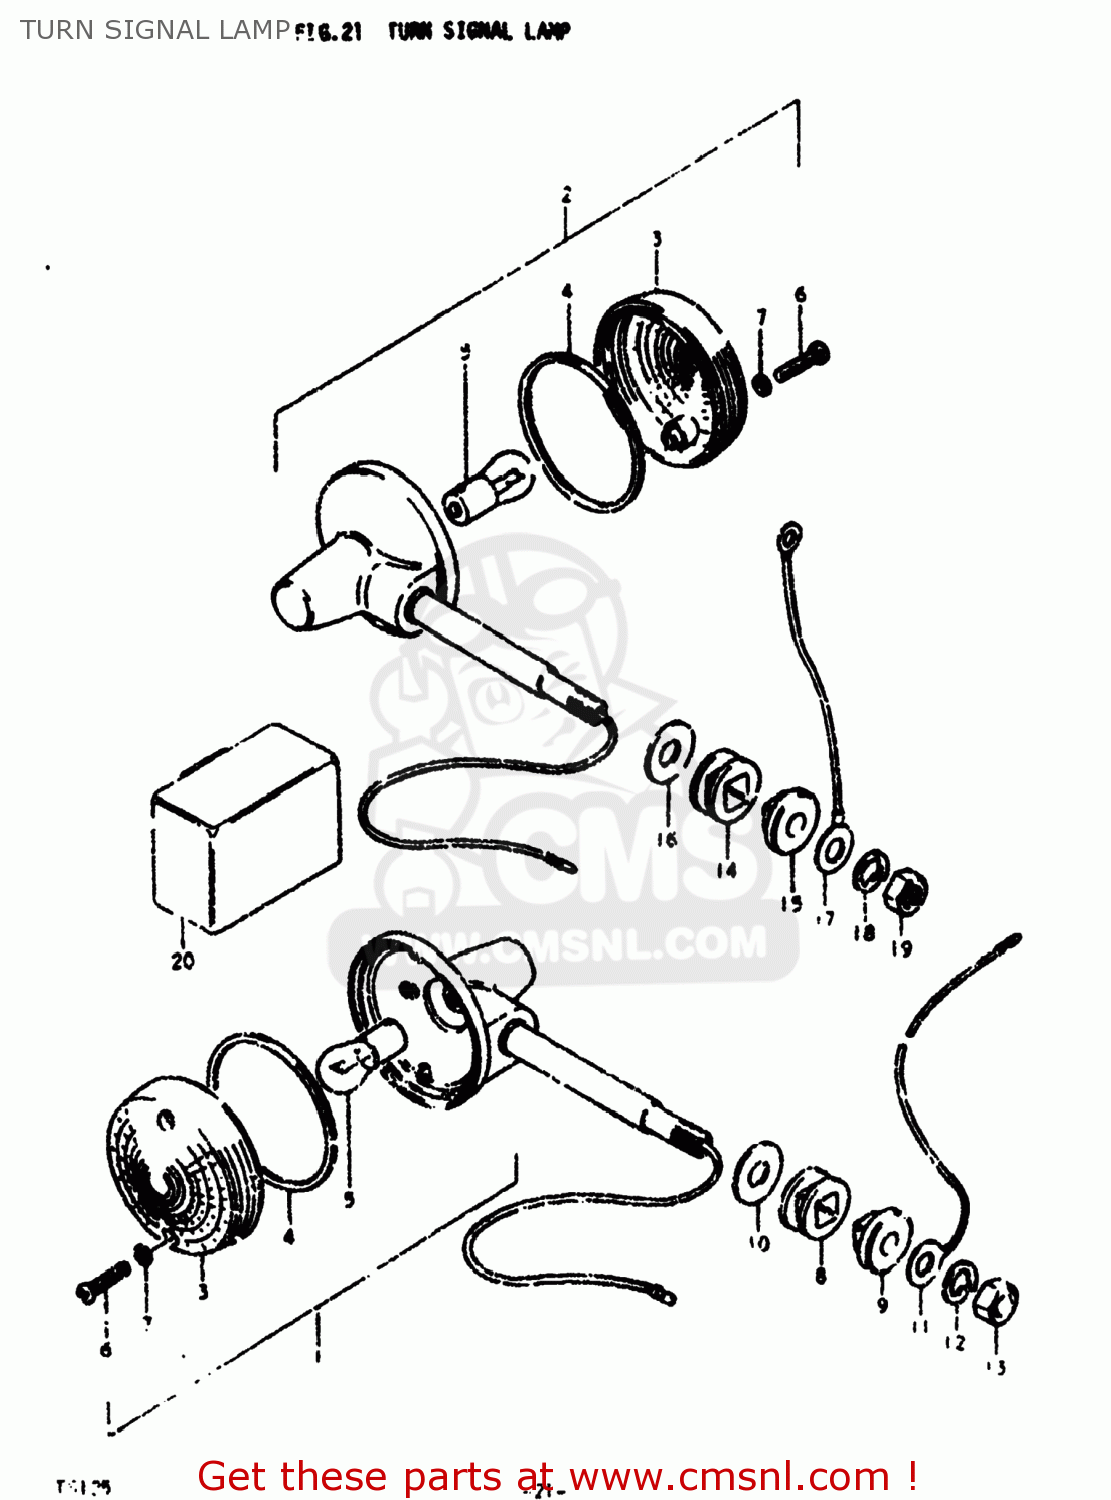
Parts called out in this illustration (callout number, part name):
1	LAMP ASSEMBLY,FRONT TURN SIGNAL
2	LAMP ASSEMBLY,REAR TURN SIGNAL
3	LENS
4	GASKET (NAS)
5	BULB(6V17W,STANLEY,A4513A)
6	SCREW
7	GASKET (NAS)
8	CUSHION
9	SPACER,RR TURNSIGNAL LAMP
10	WASHER (10.5X30X2.3)
11	LEAD WIRE,EARTH
12	LOCK WASHER
13	NUT
14	CUSHION
15	SPACER,RR TURNSIGNAL LAMP
16	WASHER (10.5X30X2.3)
17	LEAD WIRE
18	LOCK WASHER
19	NUT
20	RELAY,TURN SIGNAL
